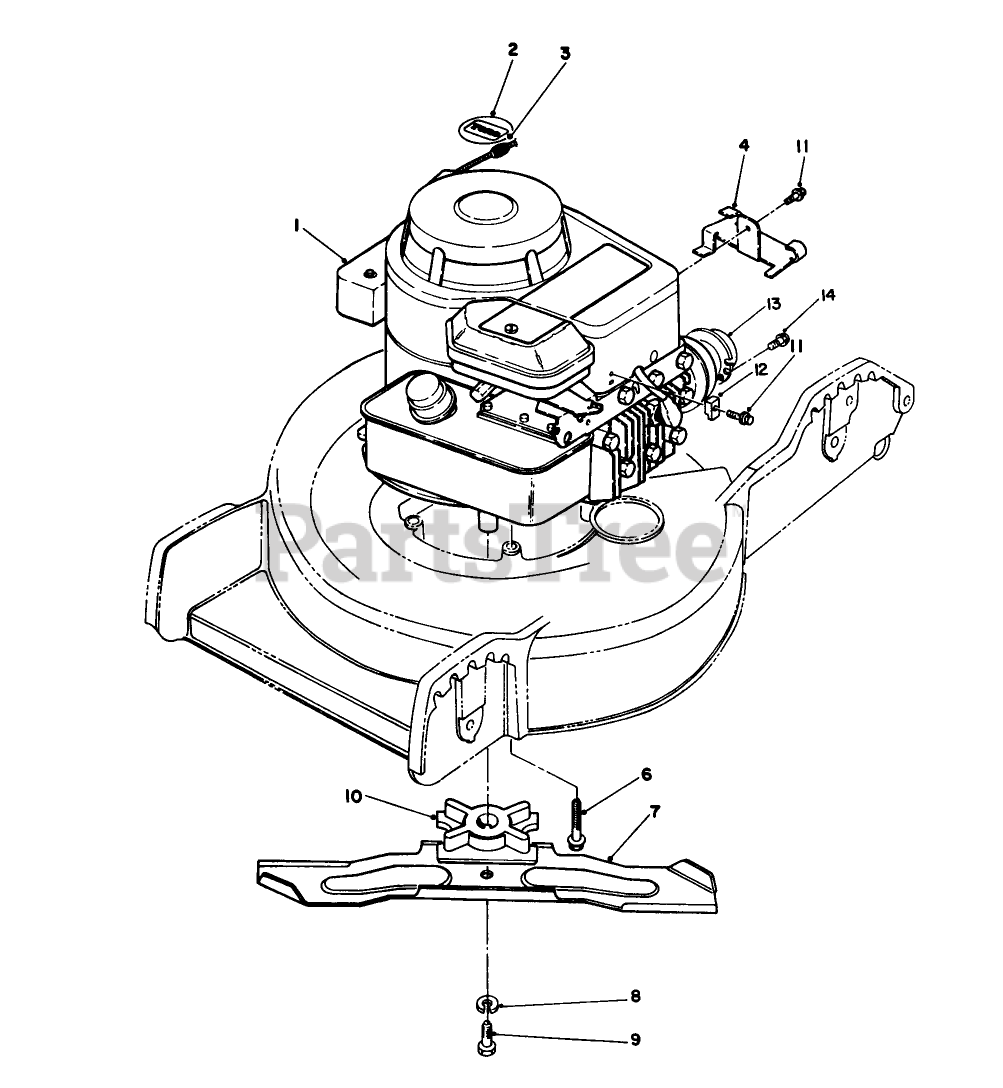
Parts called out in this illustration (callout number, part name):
1	Engine
3	STOP-ROPE
4	CABLE BRACKET *
8	WASHER-LOCK
9	SCREW-HH
10	BLADE RETAINER
11	CLAMP SCREW F/W ENGINE
12	CASING CLAMP F/W ENGINE
